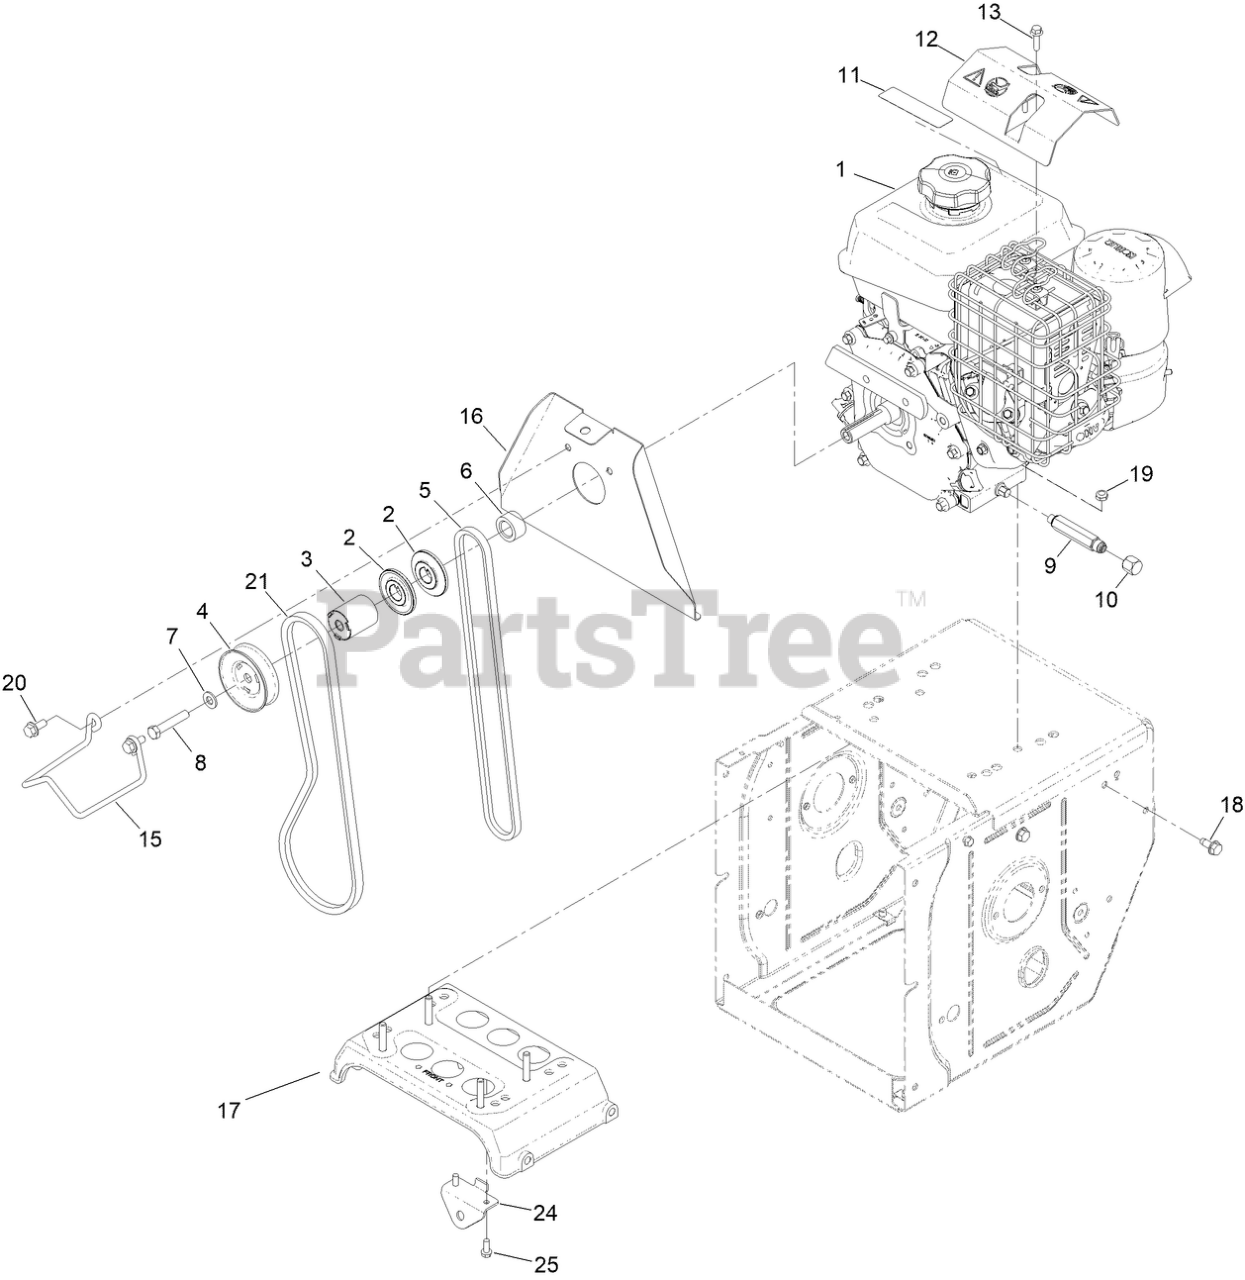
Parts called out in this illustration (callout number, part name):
2	SHEAVE-TRACTION
3	SPACER-PULLEY
4	PULLEY-IMPELLER
5	BELT,3L P21 DRIVE
6	SPACER
7	WASHER-FLAT
8	SCREW-HH
9	ADAPTER
11	DECAL-ARRESTOR, SPARK
12	DEFLECTOR,DEBRIS MUFFLER
13	SCREW-HHF
15	GUIDE-BELT
16	COVER-CRANK
17	PLATE-ENGINE, ASM
18	SCREW-HWHTF
19	NUT-HEX
20	SCREW-HH
21	V-BELT
24	BRACKET-CONTROL, TRACTION
25	SCREW-HWH
